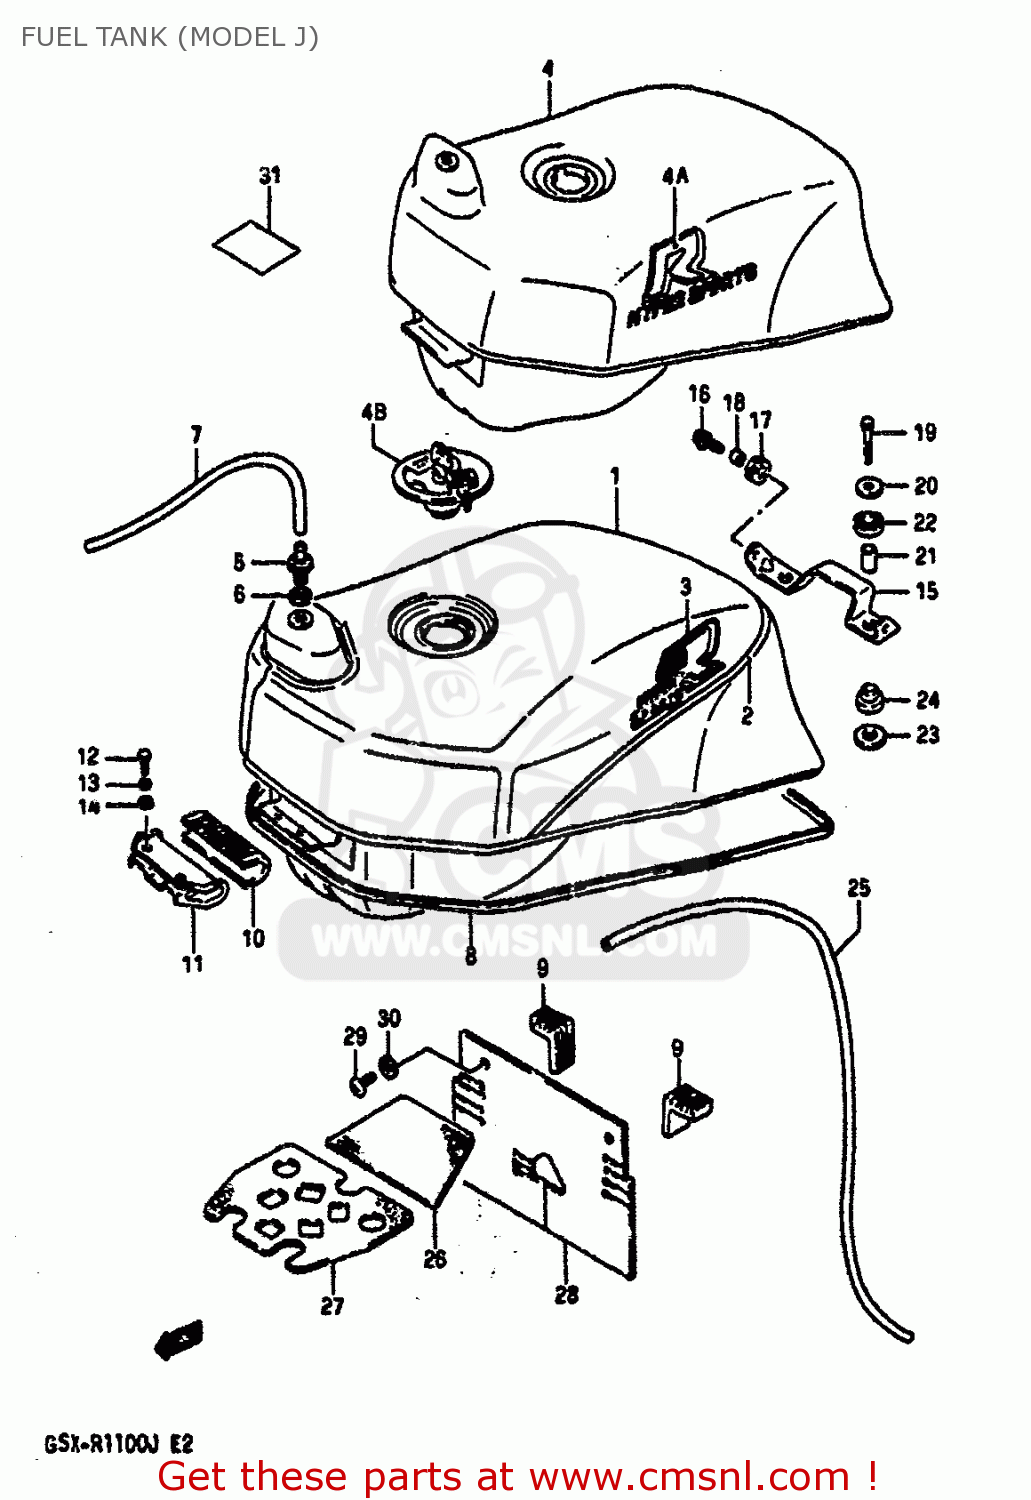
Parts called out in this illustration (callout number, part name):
1	TANK ASSEMBLY,FUEL
2	TAPE,FUEL TANK
3	EMBLEM,FUEL TANK
4	TANK,FUEL
4A	EMBLEM (GOLD)
4B	CAP SET,FUEL TANK
5	PLUG,FUEL TANK BREATHER
6	GASKET(12.5X20X2.5) (NAS)
7	HOSE
8	MOLDING,FUEL TANK
9	CUSHION,FUEL TANK SIDE
10	CUSHION,FUEL TANK FR
11	BRACKET,FUEL TANK FR
12	BOLT
13	WASHER,LOCK
14	WASHER
15	BRACKET,SEAT SUPPORT,FRONT
16	BOLT
17	CUSHION
18	SPACER(6.1X9X7.5)
19	BOLT ,6X35
20	WASHER (6.5X24X1.6)
21	SPACER
22	CUSHION
23	WASHER (12.5X24X1.6)
24	CUSHION
25	HOSE
26	SHIELD,FUEL TANK HEAT
27	SHIELD,FUEL TANK HEAT
28	SHIELD,HEAT NO.1
29	SCREW
30	WASHER
31	HOSE,FUEL
32	SHIELD,FUEL TANK HEAT
33	SHIELD,FUEL TANK HEAT
34	SHIELD,HEAT NO.1
35	SCREW
36	WASHER
37	LABEL,FUEL CAUTION
